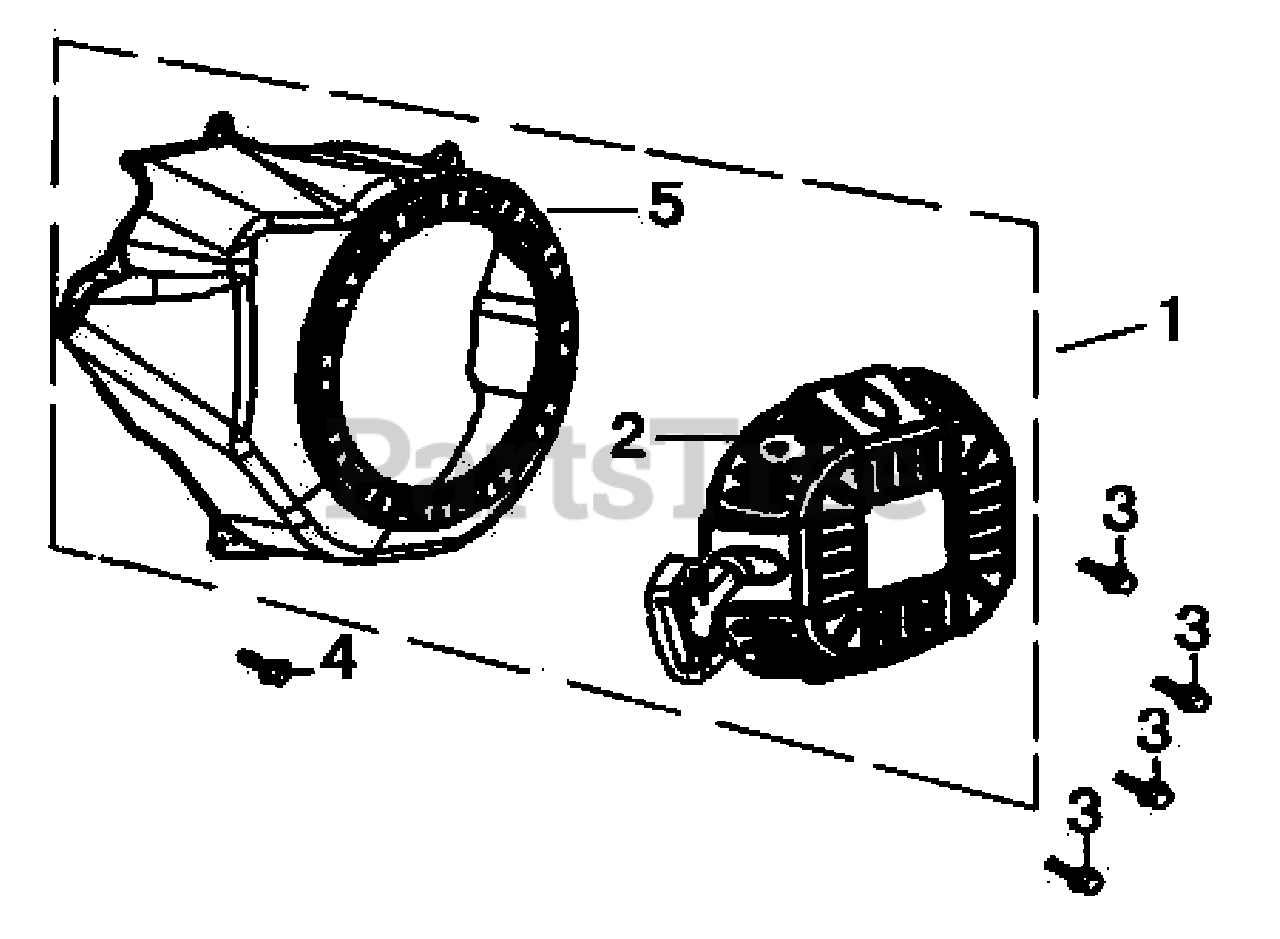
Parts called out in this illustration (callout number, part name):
1	RECOIL STARTER WITH HOUSING
2	STARTER ASSEMBLY
3	BOLT, FLANGE 6X8
4	BOLT, FLANGE 6X10
5	HOUSING, BLOWER
